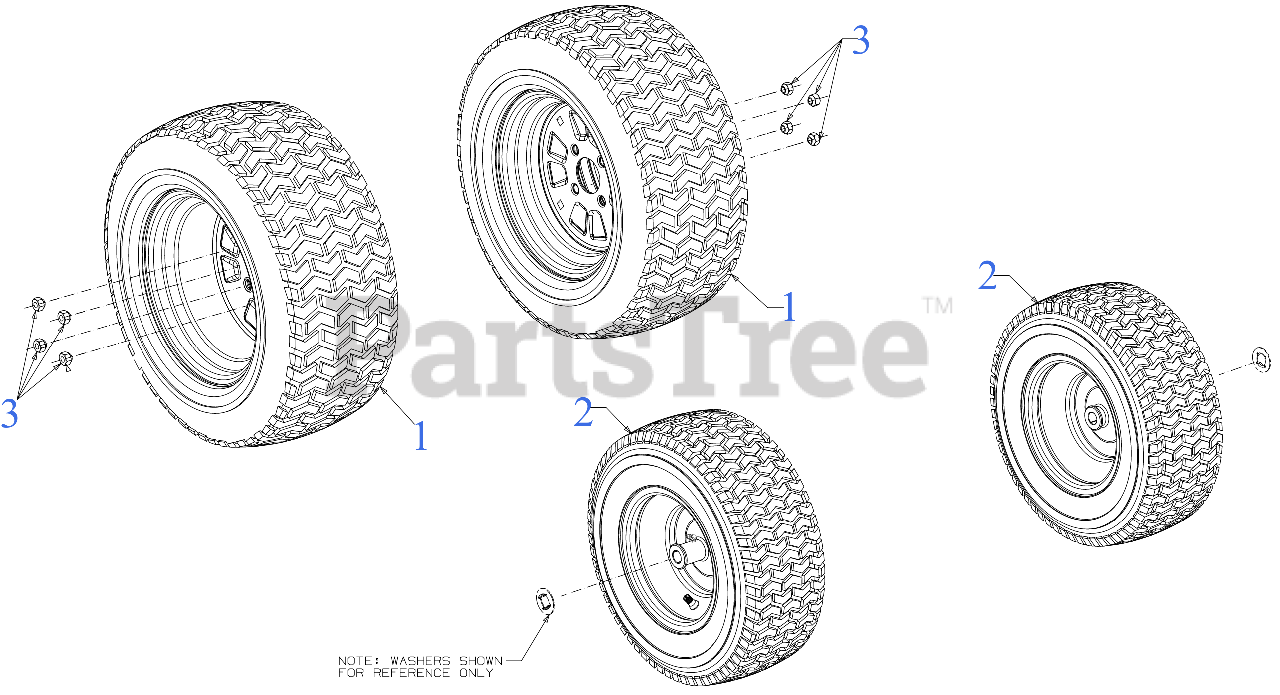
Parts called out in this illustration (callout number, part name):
2	WHEEL ASSEMBLY (16X6.5X8)
2	RIM ASSEMBLY (8.0X5.38)
3	LUG NUT 7/16-14
